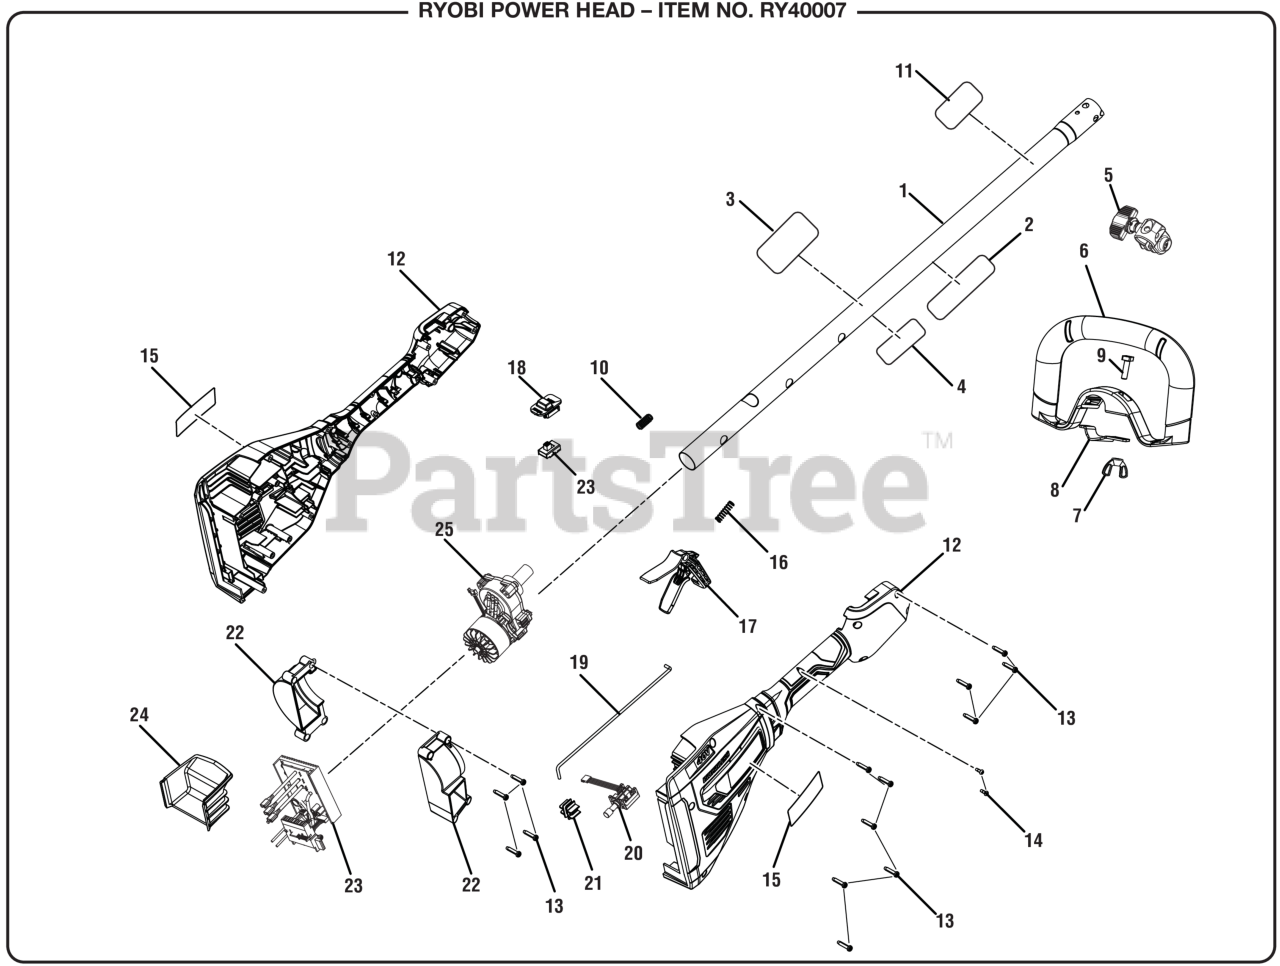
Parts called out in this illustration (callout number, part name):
1	Upper Boom Assembly
2	Warning Label (French/Spanish)
3	Warning Icon Label
4	Data Label
5	Boom Clamp Assembly
6	Front Handle Assembly
7	Wing Nut (1/4-20, Plastic)
8	Front Handle Clamp
9	Bolt (1/4-20 x 1 in., Square Hd.)
10	COMPRESSION SPRING
11	Attachment Label
12	Rear Handle Assembly
13	Screw (M4 x 18 mm, T15 Torx Pan Hd.)
14	Screw (M3 x 8 mm, Pan. Hd.)
15	Logo Label
16	Compression Spring (Trigger Lock)
17	Switch Trigger Assembly w/Lock-Out
18	Slide Switch Cover
21	Switch Cap
22	Motor Volute Assembly
23	Electric Controller and Switch Assembly
24	Bucket Housing
25	Motor and Gear Box Assembly
